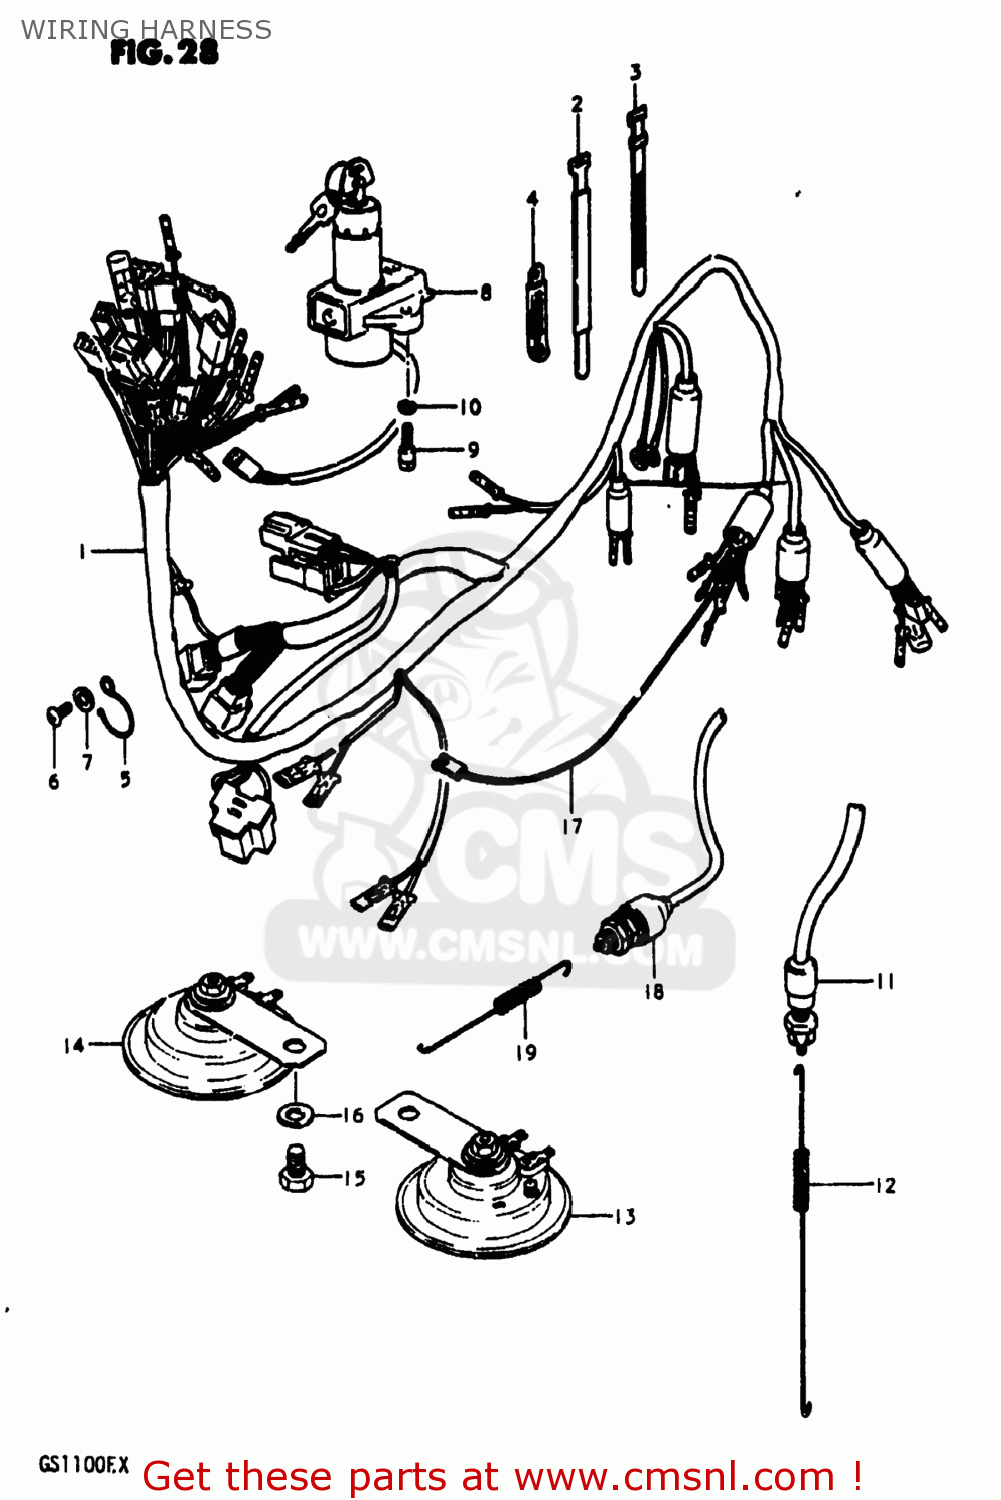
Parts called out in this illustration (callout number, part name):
1	WIRING HARNESS
2	CLAMP
3	CLAMP(L:120)
4	CLAMP
5	GUIDE,WIRING HARNESS
6	SCREW 6X12
7	WASHER
8	LOCK ASSEMBLY,STEERING
9	BOLT
10	LOCK WASHER
11	SWITCH ASSEMBLY,STOP LAMP
12	SPRING
13	HORN ASSEMBLY,LOW PITCH
14	HORN ASSEMBLY,HIGH PITCH
15	BOLT 8X12
16	WASHER
17	WIRE
18	SWITCH ASSY,SIDE STAND WARNING
19	SPRING
20	KEY,BLANK
